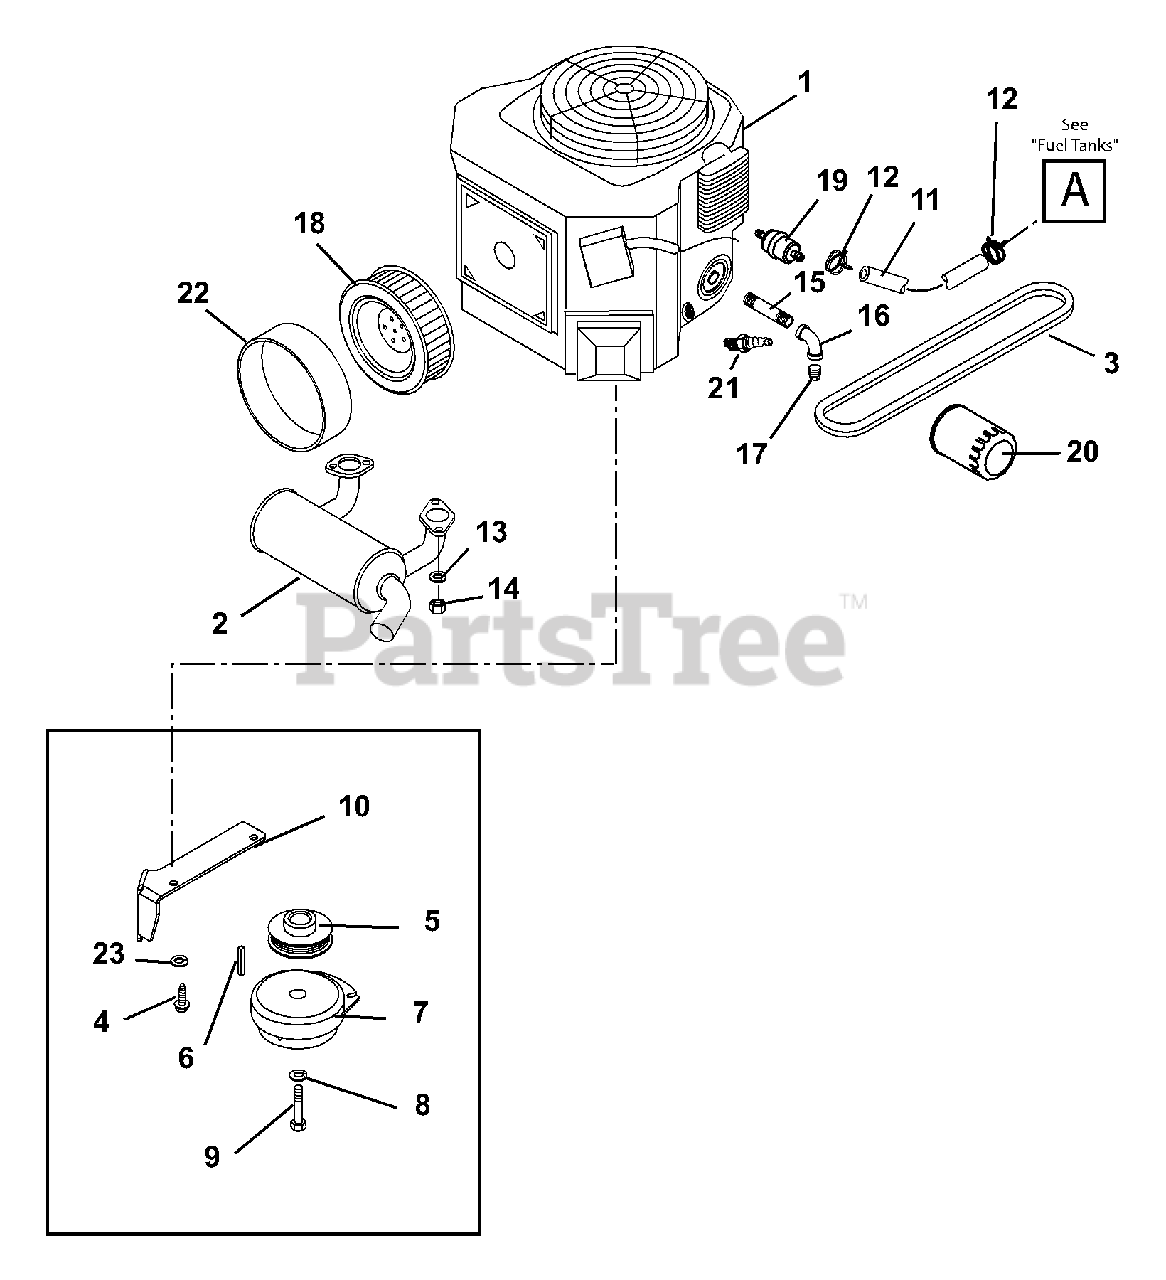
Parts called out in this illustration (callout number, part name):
1	Engine, Kohler, 23hp
2	Muffler, Kohler
3	V-Belt HA 52 x .535 G48667
4	Bolt, 38-16X1 6-LOBE PH TRX YZ
5	Pulley-V 4.00 x 1.125 with Key 1.42 Height
6	Key, Square .25 x .625 x .25 SAE 8630 OR SAE 1035
7	Clutch, Electric
8	Washer, Locking .44 x .109
9	Bolt, Hex .44-20 x 2.25 Grade 5
10	Clutch Stop
11	Gas Line, Bulk .25 ID
12	Hose, Clamp
13	Washer, Lock .31 x .078 Regular
14	Nut, Hex M8-1.25
16	Elbow .375-18
17	Pipe Plug
19	Fuel Filter, Kohler
20	Oil Filter, Kohler
21	Spark Plug, Kohler
23	Washer, Lock .31 x .078
